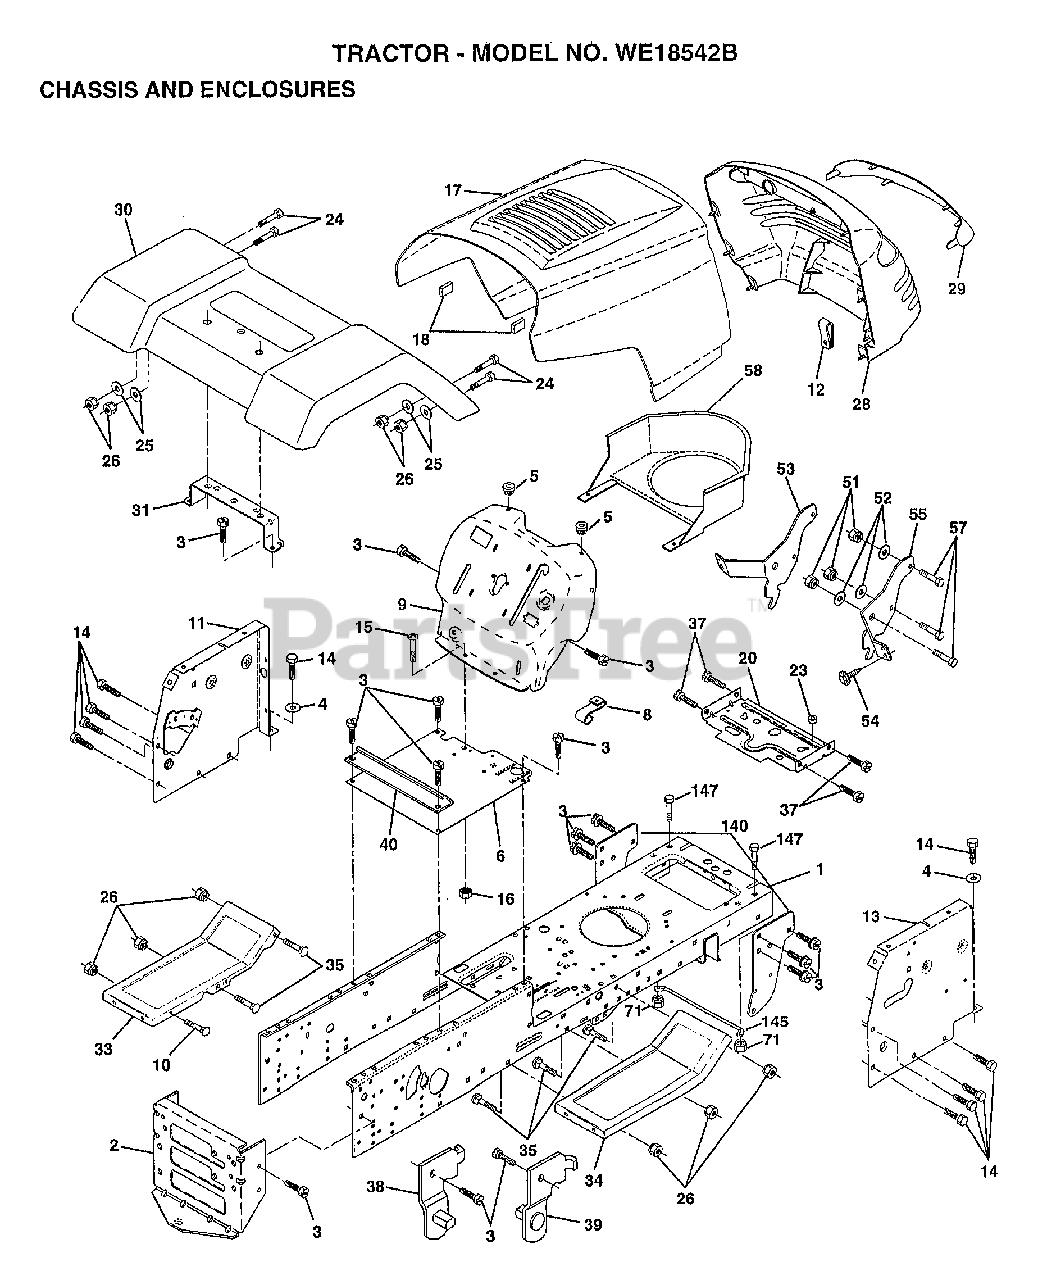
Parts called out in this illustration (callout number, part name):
1	CHASSIS ASM
3	SCREW
4	WASHER
5	BUMPER-HOOD/DASH
6	SADDLE
8	CLIP.RETAINER
9	DASH.SILKSCREENED
11	"PANEL-DASH,LH"
12	CLIP.TINNERMAN
14	SCREW LT
15	SCREW
20	"PLATE-MTG,BATT/FU"
24	BOLT
25	WASHER
26	NUT
28	GRILLE-MS428
29	LENS GRILLE
30	FENDER
31	BRACKET SUPT FEND
33	FOOTREST.LH.LT/GT
34	FOOTREST.RH.LT/GT
35	BOLT
37	SCREW LT
38	BRACKET ASM LH
39	BRACKET ASM RH
40	SPACER FENDER LT
51	NUT
52	WASHER
53	BRACKET.GRILLE.LH
55	BRACKET.GRILLE.RH
58	DUCT.AIR.B&S.18HP
140	BRKT SUSPENSION
145	"ROD POVOT,CHASSIS"
147	BOLT LT
